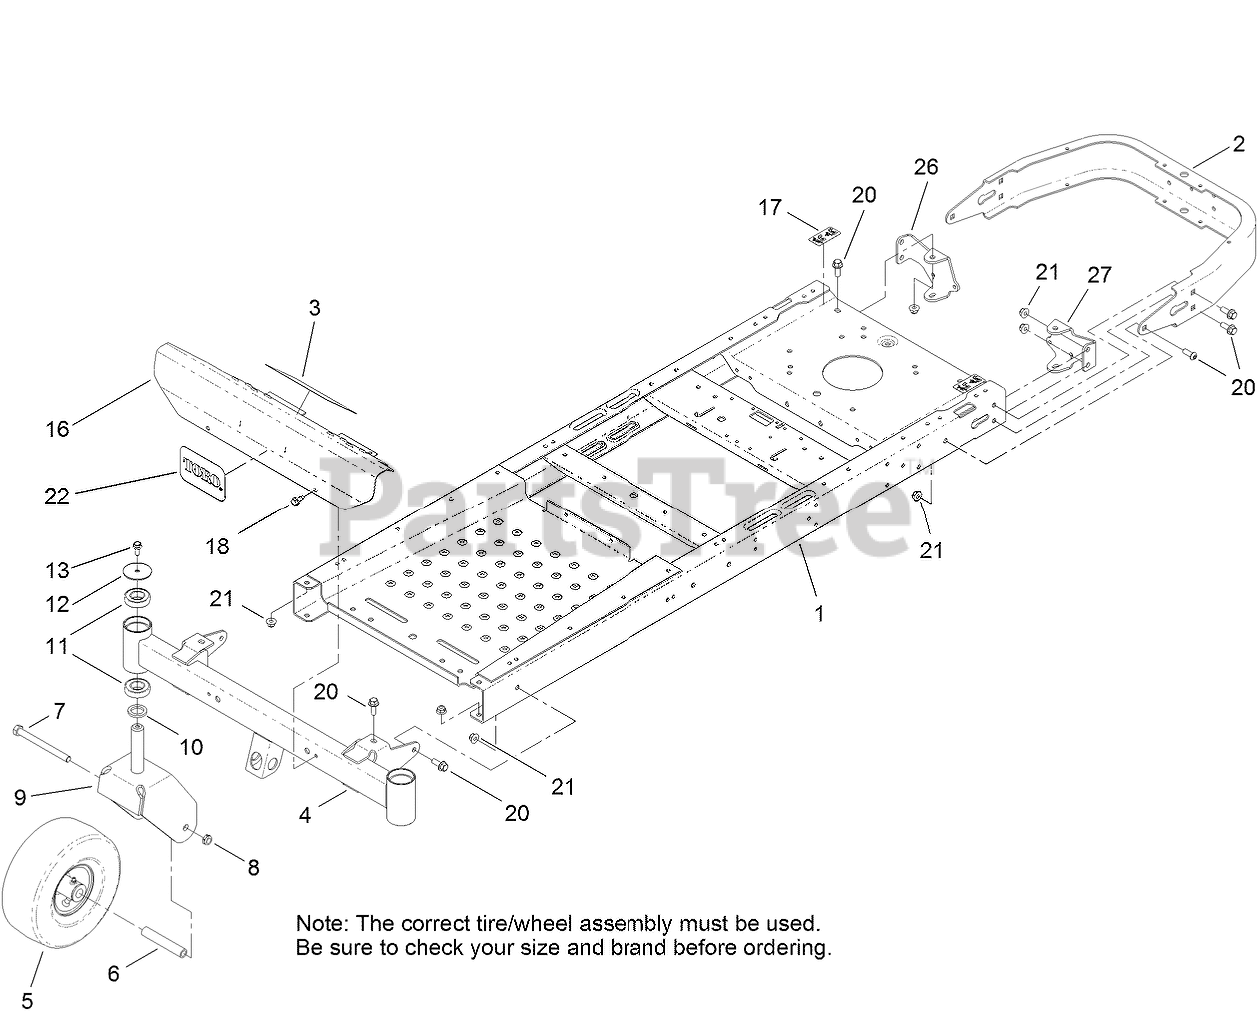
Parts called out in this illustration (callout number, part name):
2	BUMPER-REAR
3	DECAL-DANGER
4	AXLE-FRONT
5	CASTER WHEEL ASM (CST)
5	CASTER WHEEL ASM (Kenda)
6	BUSHING-SPANNER
7	SCREW-HH
8	NUT-LOCK, NI
9	FORK-CASTER
10	WASHER-THRUST
11	BEARING-BALL
12	WASHER
13	SCREW-HHF
16	FOOTREST
17	DECAL-BYPASS
18	SCREW-HWHTF
20	SCREW-HHF
21	NUT-HF, NI
26	MOUNT-HYDRO, REAR (RH)
27	MOUNT-HYDRO, REAR (LH)
